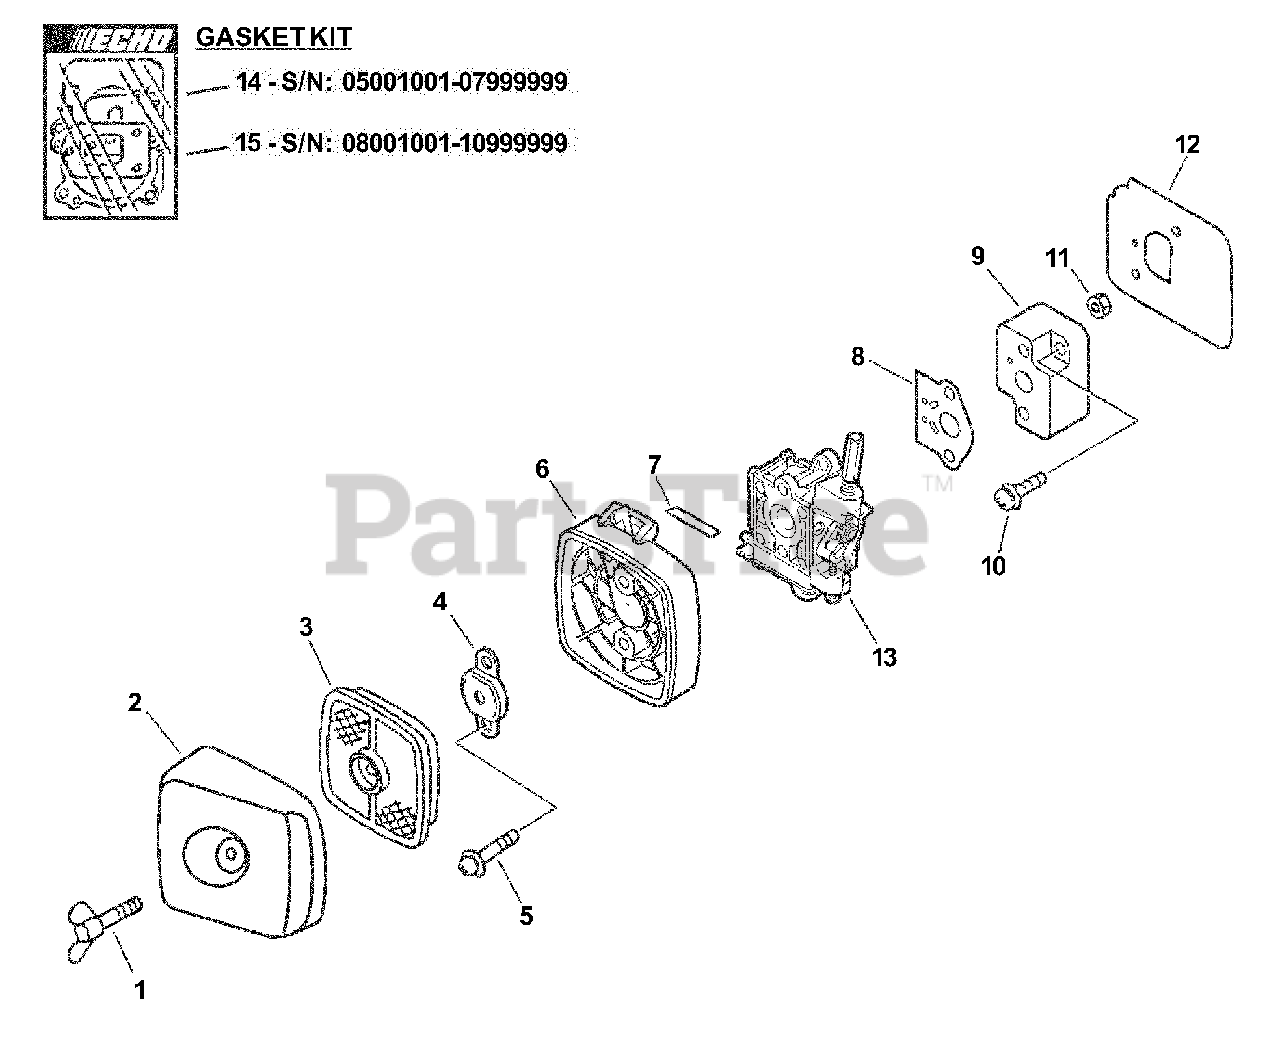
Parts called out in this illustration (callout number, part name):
1	BOLT, WING 5×20
2	COVER, AIR FILTER - GRAY
3	FILTER, AIR - SINGLE LAYER
4	PLATE, PREVENT
5	SCREW 5×65
6	CASE, AIR FILTER - GRAY
7	LABEL, CHOKE
8	GASKET, CARBURETOR
9	INSULATOR, INTAKE
10	SCREW 5×20
11	NUT M5
12	HEAT SHIELD, INTAKE
13	CARBURETOR
14	GASKET KIT
15	GASKET KIT
